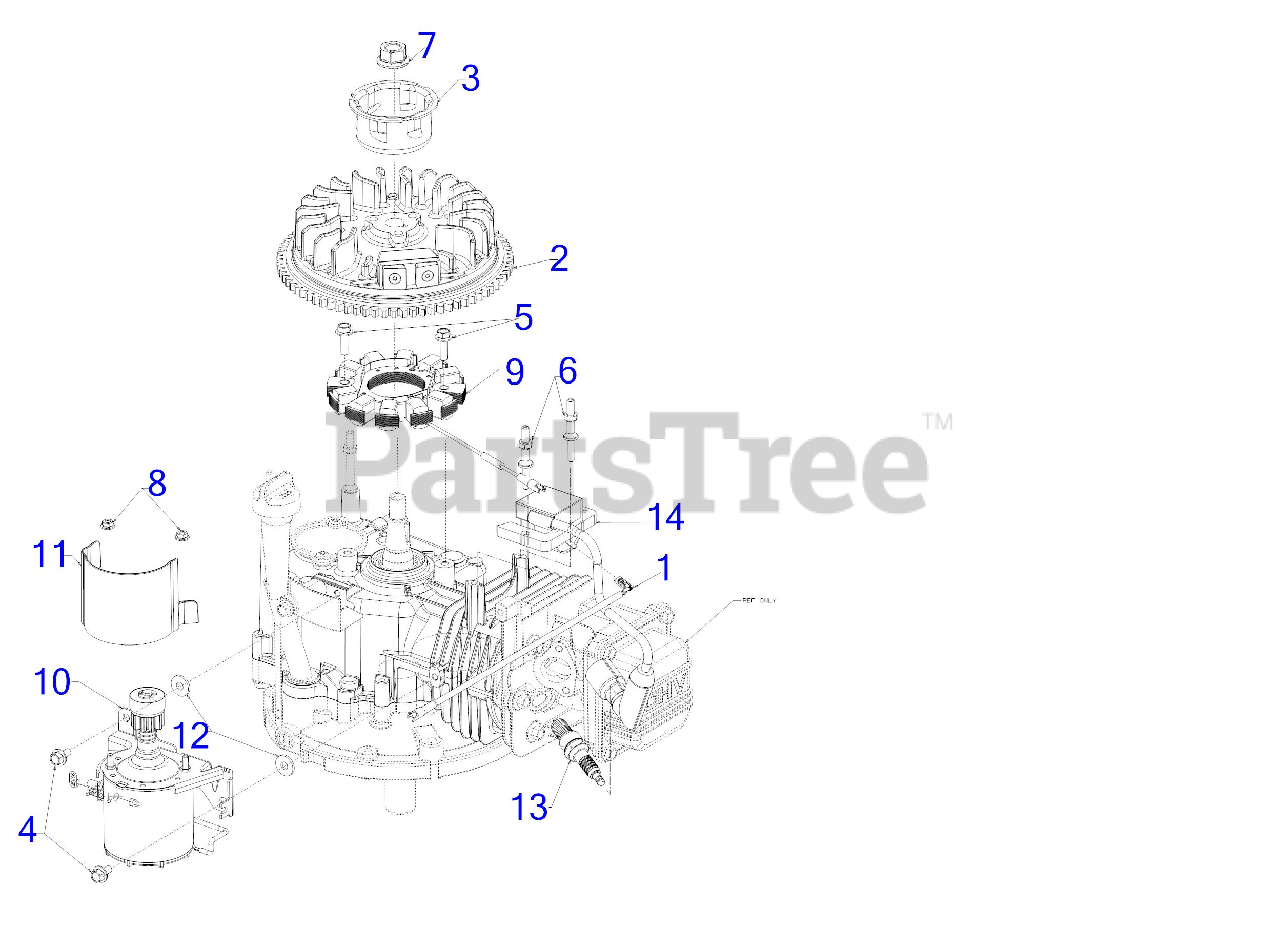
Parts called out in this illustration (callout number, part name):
1	WIRE HARNESS
4	SCREW M6-1 x 12 CL8.8
5	SCREW M6-1 x 20 CL5.8
6	STUD M5-8:22
7	HEX FLANGE NUT
8	HEX FLANGE NUT M5-0.8
9	ALTERNATOR ASSEMBLY
10	ELECTRIC STARTER MOTOR
11	GEAR COVER
12	FLAT WASHER: 6.5X18X2
13	SPARK PLUG
14	IGNITION MODULE
